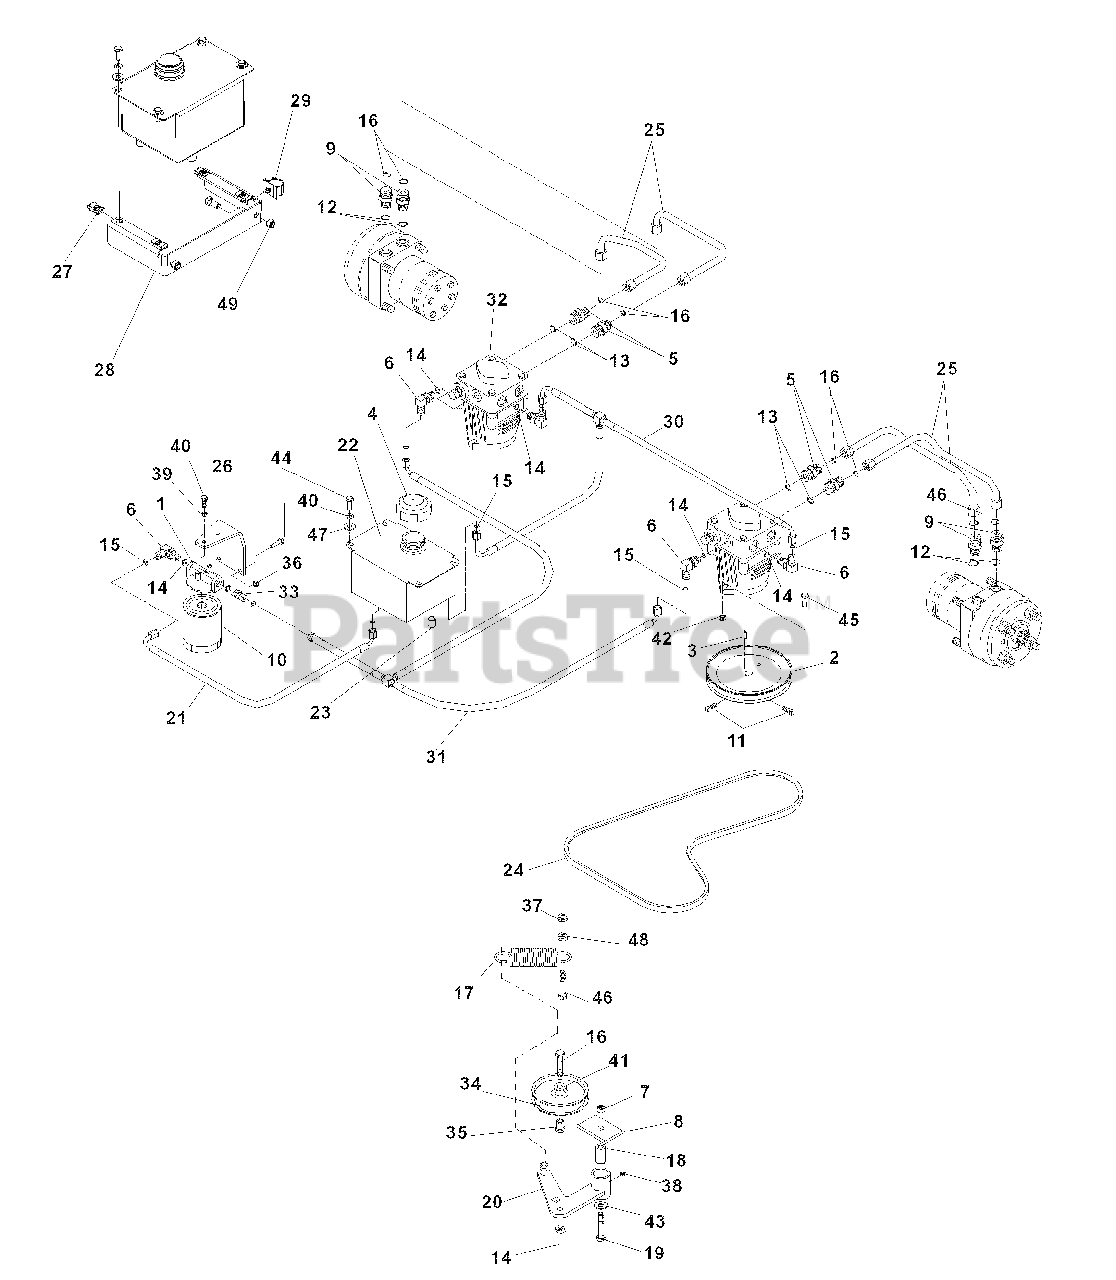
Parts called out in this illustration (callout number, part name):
1	FILTER HEAD
3	KEY, 5MM SQ x 30MM
4	CAP-HYDRO RESERVOIR
5	FITTING, F6400-8-8-0
6	FITTING, F6801-6-6-0
7	NUT, 1/2 -13, NYLOC
9	STRAIGHT FITTING
10	FILTER ELEMENT
11	SCREW, 5/16-18 x 5/8
12	"O" RING, 3/4
13	"O" RING, 1/2
14	"O" RING, 3/8
15	"O" RING FLARE, 3/8
16	"O" RING FLARE, 1/2
17	SPRING, EXTENSION
18	BUSHING, PIVOT
19	HCS, 1/2 -13 x 3 1/4
20	IDLER ARM
24	PUMP BELT
25	HYDRAULIC LINE
26	OIL FILTER BRACKET
27	"U" TYPE RETAINER
28	TANK MOUNT
30	"T" ASSEMBLY
31	"T" ASSEMBLY
32	10CC PUMP W/RTN’S
33	HYDRAULIC FITTING
34	PULLEY, IDLER
35	BUSHING, FLANGE IDLER
36	NUT, 1/4 -20, NYLOC
37	NUT, 3/8 -16, NYLOC
38	ZERK, STRAIGHT, 1/4 -28
39	LOCKWASHER, 1/4
40	HCS, 1/4 -20 x 5/8
41	WASHER, 3/8
42	NUT, 3/8 -16, CENTERLOCK
43	WASHER, 9/16
44	HCS, 1/4 -20 x 3/4
45	HCS, 3/8 -16 x 1, WHIZLK
46	HCS, 3/8 -16 x 2
47	WASHER, 1/4
48	NUT, 3/8 -16, WHIZLK
49	5/16 NYLOC NUT
50	HCS, 3/8 -16 x 1 3/4
51	HYDRAULIC MOTOR W/RTNS
